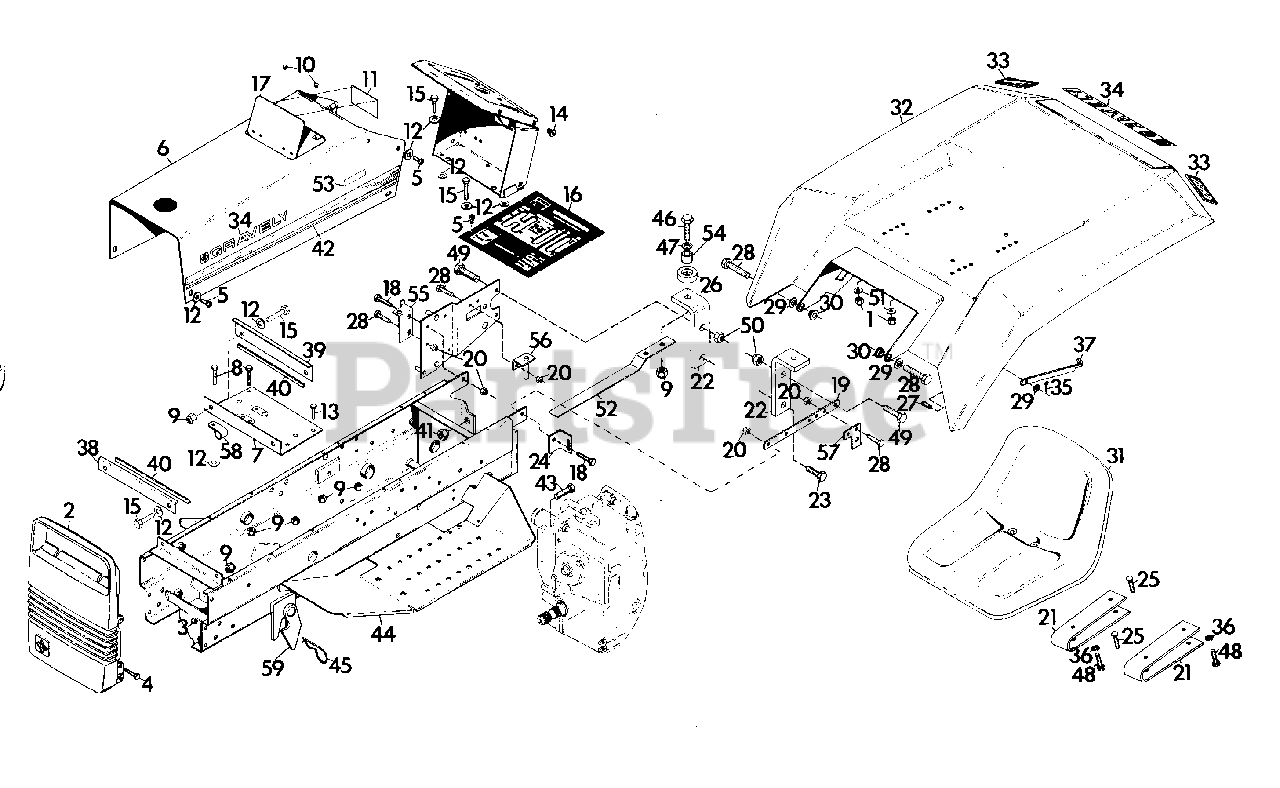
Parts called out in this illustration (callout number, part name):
1	NUT, LOCK 5/16-18
2	CASTING, GRILLE
3	NUT, LOCK 5/16-18
4	BOLT, HEX 5/16-18X1.25
5	SCREW, TAPPING 1/4-20X.5 PAN HD CR
6	ASM., HOOD 8122, 8123 AND 8163-B
6	ASM., HOOD 8179-KT AND 8199-KT
7	TRAY, BATTERY
8	BOLT, HEX 1/4-20X.625
9	NUT, LOCK 1/4-20
10	PLUG, BUMPER
11	DECAL, ELECTRICAL SYSTEM WARNING
12	WASHER, FLAT .281X.625X.065
13	BOLT, HEX 1/4-20X.875
14	GROMMET, PLASTIC
15	BOLT, HEX 1/4-20X.75
16	PLATE, CONTROL COVER 8122
16	PLATE, COVER
17	ASSEMBLY, DOOR
18	BOLT, HEX 3/8-16X1.25
19	STRAP, FRAME EXTENSION
20	NUT, LOCK 3/8-16
21	SPRING, SEAT
22	BRACKET, REAR HITCH
23	BOLT, HEX 1/2-13X1.25
24	BRACKET, FENDER HOLD-UP
25	BOLT, CARRIAGE 5/16-18X.75
26	BUMPER, SEAT
27	PIN, CLEVIS .250X.406
28	BOLT, HEX 3/8-16X1
29	WASHER, FLAT .406X.812X.065
30	BUSHING, REAR FENDER
31	SEAT, HIGH BACK
32	WELDMENT, SEAT PAN
32	WELDMENT, SEAT PAN W/NOTCH
33	REFLECTOR, RED SAFETY
34	DECAL, GRAVELY LOGO
35	PIN, COTTER .06X.75
36	WASHER, LOCK 5/16 REG.
37	STRAP, FENDER HOLD-UP
38	BRACKET, FORWARD TANK
39	BRACKET, REAR TANK
40	MOULDING
41	NUT(RIM)
42	DECAL, SIDE STRIPE
42	DECAL, SIDE STRIPE PROF.
43	BOLT, HEX 1/2-20X1.5
44	WLDMT., FRAME 8122, 8123 AND 8163-B
44	WLDMT., FRAME 8179-KT AND 8199-KT
45	PIN, HAIR
46	BOLT, HEX 1/4-20X1.50
47	WASHER, FLAT .312X.734X.065
48	BOLT, HEX 5/16-18X.75
49	BOLT, HEX 1/2-13X1.5
50	NUT, LOCK 1/2-13
51	WASHER, FLAT .375X1.125X.065
52	SPRING, CLUTCH DETENT
53	DECAL, 8122
53	DECAL, 8123
53	DECAL, 8179-KT
53	DECAL, 8163-B
53	DECAL, 8199-KT
54	BUSHING, .259X.375X.25
55	BRACKET, INTERLOCK SWITCH
56	WELDMENT, CLUTCH ARM BRACKET
57	BRACKET, CLUTCH SLIDE ROD
58	CLAMP, NYLON
59	WELDMENT, MOWER BRACKET L.H.
59	WELDMENT, MOWER BRACKET R.H.
NS	DECAL, AMERICA
